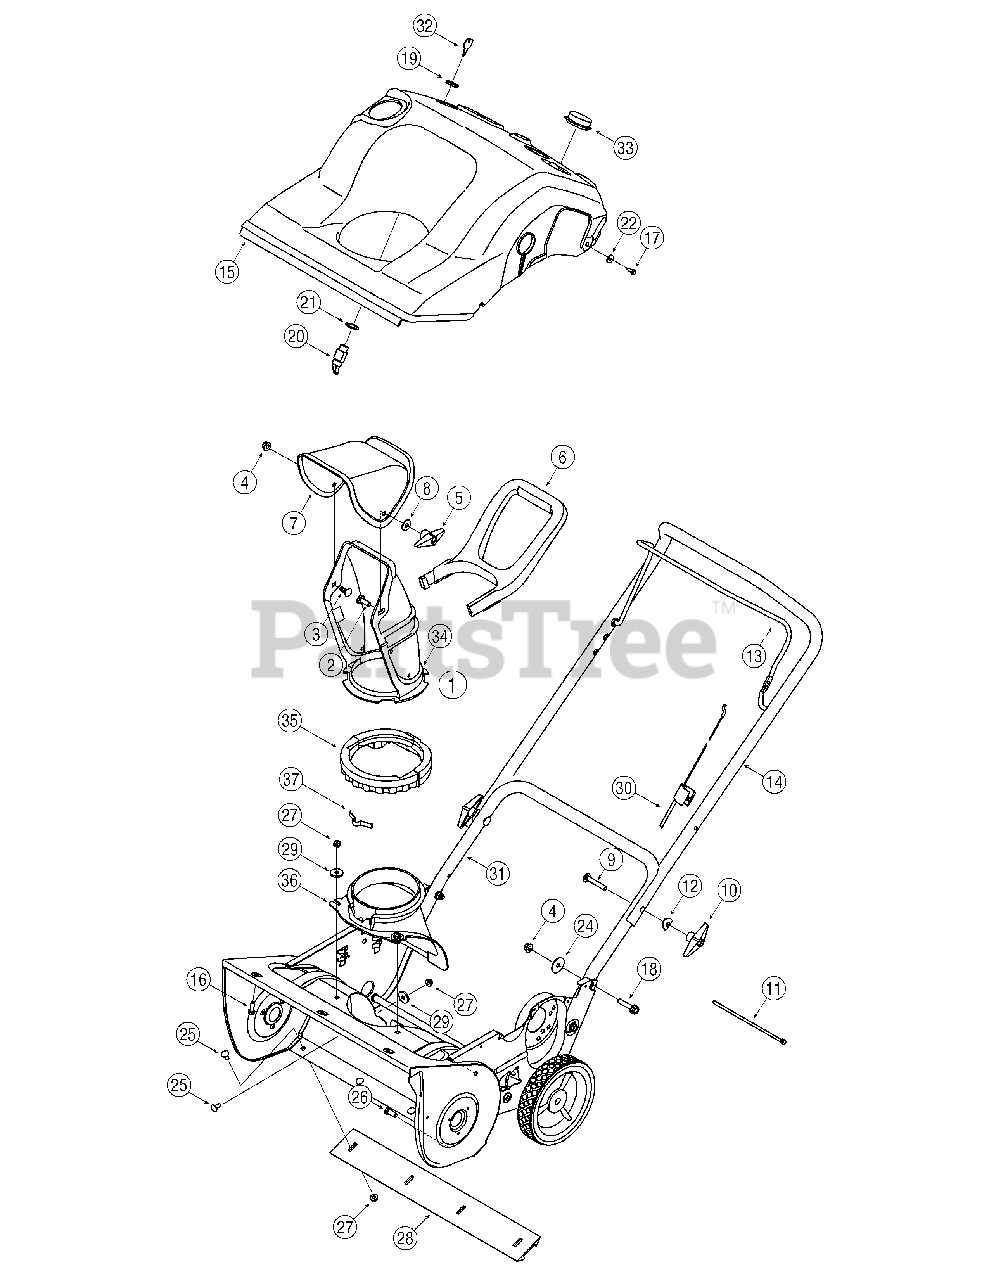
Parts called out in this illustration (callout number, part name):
1	Chute Assembly
2	Carriage Bolt 5/16-18 x 1.0"
3	Carriage Bolt 5/16-18 x 0.750"
4	Flange Lock Nut, 5/16-18
5	Chute Knob Assembly
7	Upper Chute
9	Carriage Bolt 5/16-18 x 2.0 Gr. 1
10	Handle Knob Assembly 5/16-18
12	Saddle Washer .320 x .93
15	Shroud Assembly 2 Cyc. 5.5hp.
16	Screw, 1/4-15 x .50
17	Self-tapping Screw, #10-16 x .625"
18	Hex Flange Screw 5/16-18 x 1.50 Gr. 5
19	Hex Nut 5/8-32 x .12 Special
20	Key Switch-Electric Start
21	Lock Washer Internal .625 x 1.058
22	Flat Washer .194" x .62" x .063
23	Extension Spring
24	Flat Washer .330 x 1.25 x .06
25	Screw, 1/4-20 x .62
26	Truss Machine Screw, 5/16-18 x .75
27	Hex Flange Lock Nut, 1/4-20
28	Shave Plate,19.88
29	Flat Washer .265 x .938 x .120
30	Control Cable
32	Ignition Key
33	Spark Plug Cover
34	Lower Chute 5" Dia
35	Ring-Lower Chute
36	Chute, Adapter 5" Dia
37	Chute Adjustment Spring
